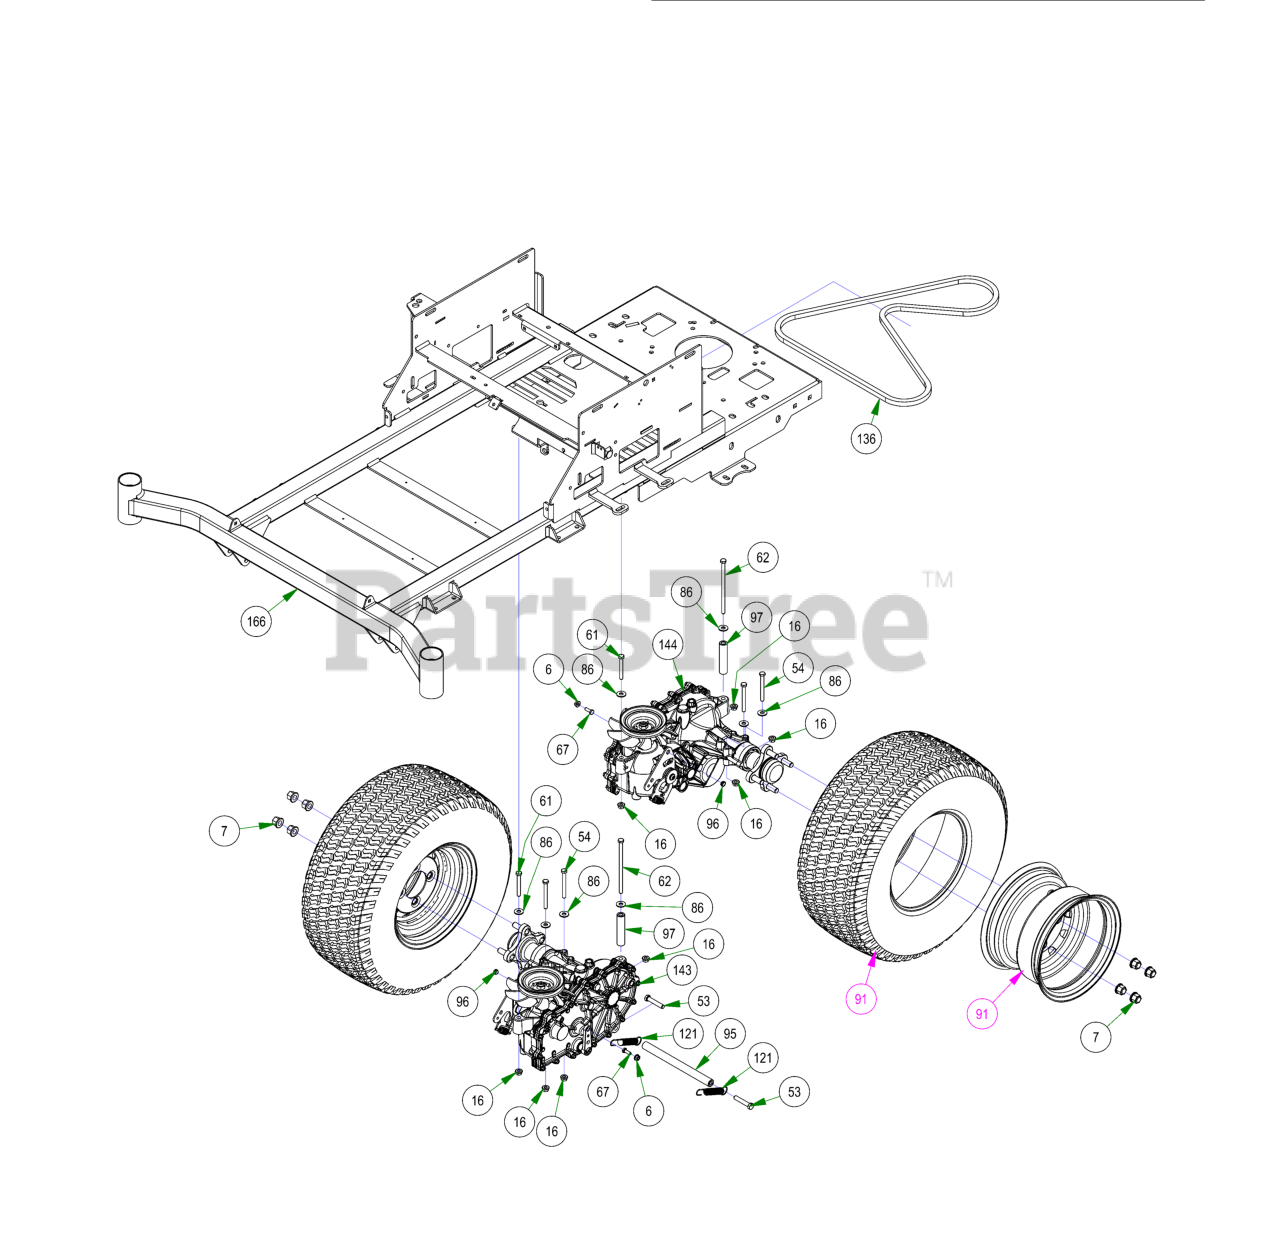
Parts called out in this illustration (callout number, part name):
6	1/4-20 NYL INSERT FLANGE LOCKNUT ZINC
7	Acorn Lug Nut
16	5/16-18 NYLON INSERT FLANGE LOCKNUT ZINC
53	3/8-16 X 2 HEX CAP SCREW (GR.5) ZINC
54	5/16-18 X 3 HEX CAP SCREW (GR.5) ZINC
61	5/16-18 X 2-1/2 HEX CAP SCREW (GR.5) ZINC
62	5/16-18 X 6 HEX CAP SCREW (GR.5) ZINC
67	1/4-20 X 3/4 HEX CAP SCREW (GR.5) ZINC
86	5/16 USS FLAT WASHER (7/8 OD) ZINC
91	ZT Tire and Rim Assembly 22 x 11 - 10
95	2017 Transaxle Spacer-ZT
96	Drive Arm Transaxle Spacer
97	2017 Transaxle Spacer
121	Brake Return Spring
143	2021 RH 2800 Transaxle
144	2021 LH 2800 Transaxle
166	2022 MZ/ZT 54"-60" Frame
